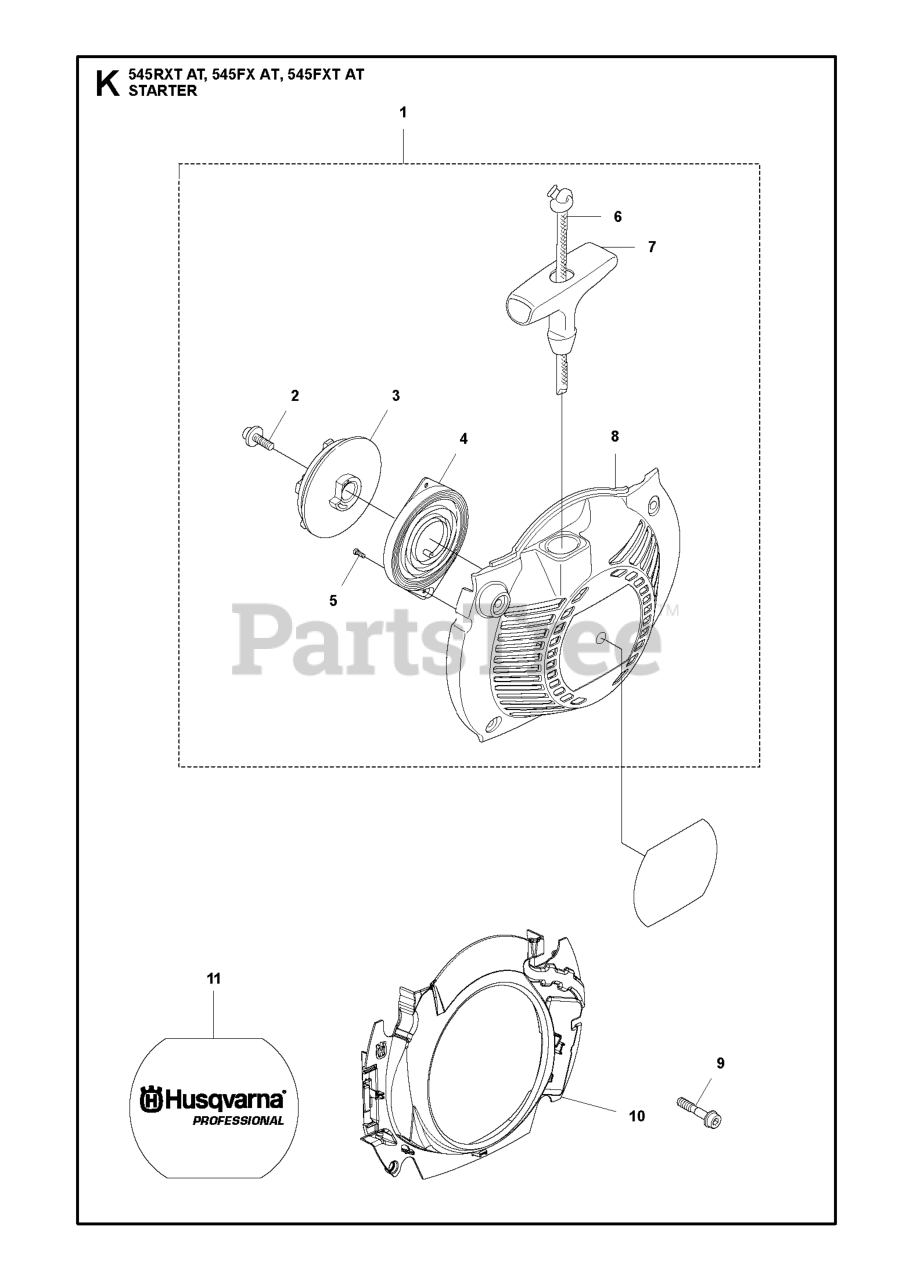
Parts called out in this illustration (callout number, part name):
3	STARTER PULLEY
4	RECOIL SPRING
6	STARTER ROPE
8	STARTER ASSY
9	SCREW IHSCFMO
10	COOLING AIR CONDUCTOR COOLING
